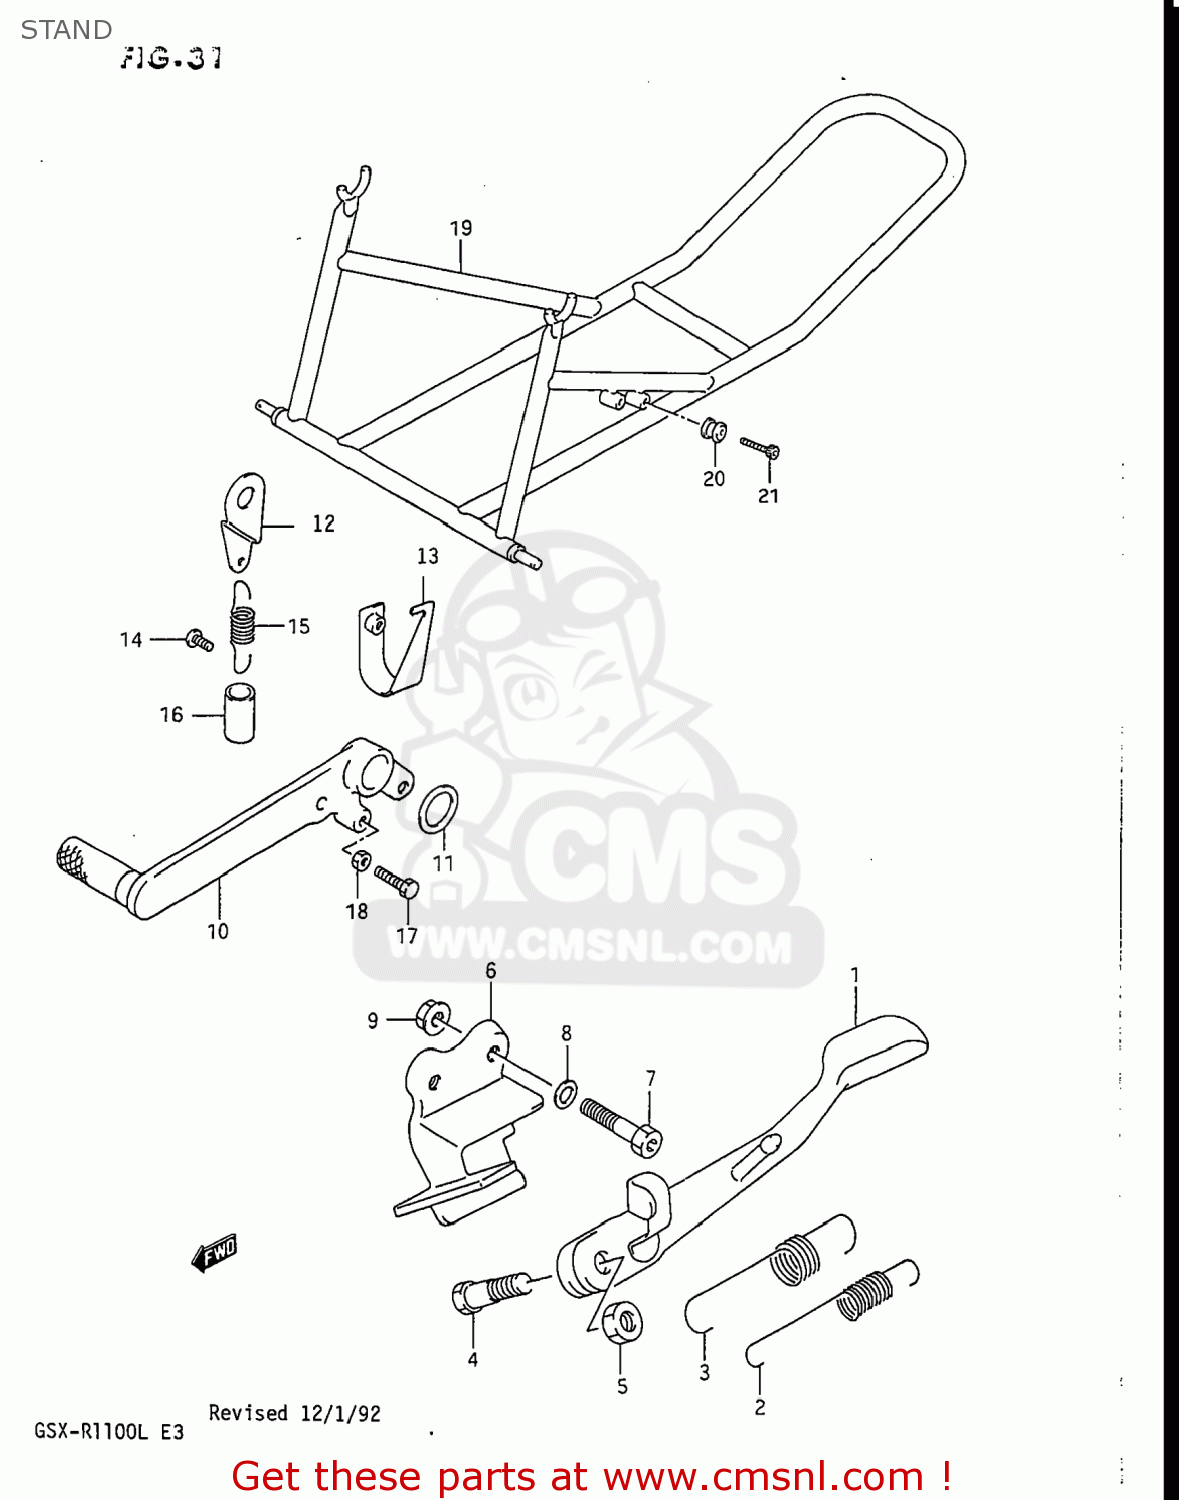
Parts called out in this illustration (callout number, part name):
1	STAND,PROP
2	SPRING
3	SPRING
4	BOLT(10X38)
5	NUT
6	BRACKET,PROP STAND
7	BOLT, FRONT RH
8	WASHER
9	NUT
10	PEDAL,BRAKE
11	WASHER(18X24X1)
12	PLATE,BRAKE SPRING,FRONT
13	BRACKET,STOP SWITCH SPRING
14	SCREW(6X12)
15	SPRING
16	TUBE,BRAKE SPRING GUIDE
17	BOLT
18	NUT
19	STAND ASSEMBLY,REAR
20	HOLDER,STAND
21	BOLT, REAR (8X30)
